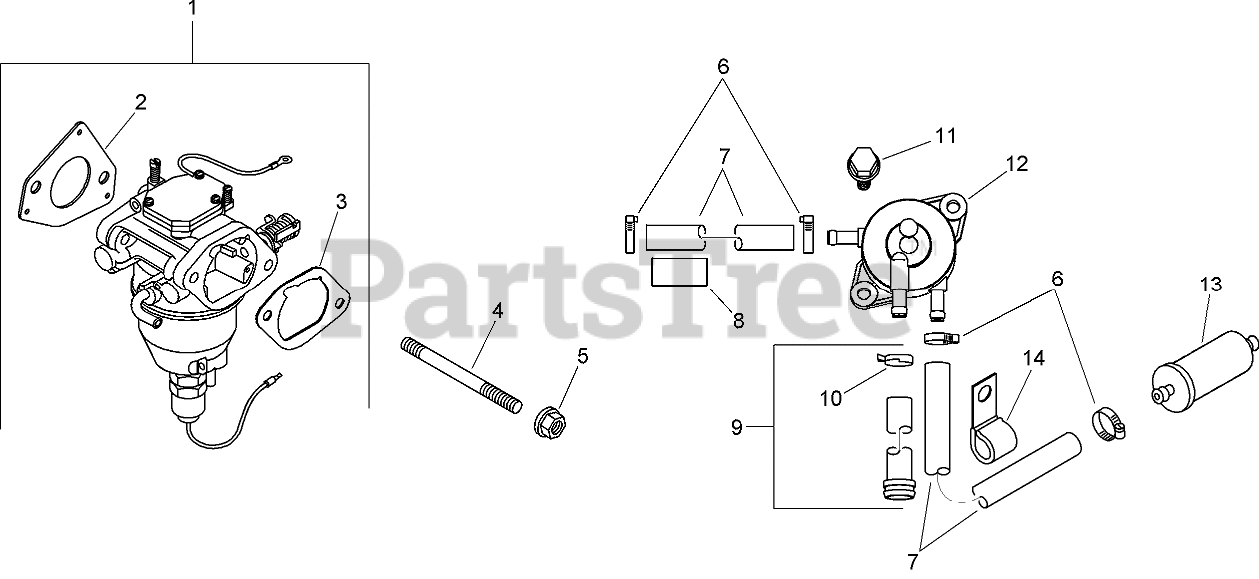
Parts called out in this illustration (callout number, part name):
1	CARBURETOR KIT W/GASKETS (INCLUDES 2, 3)
2	GASKET-CARBURETOR
3	GASKET-BASE, AIR CLEANER
4	STUD (M6X1.0X106)
5	NUT-FLANGE (M6X1.0)
6	CLAMP-HOSE, SPRING (1/2)
7	LINE-FUEL (24.0 CUT TO LENGTH)
8	SLEEVE-ABRASION, ANTI
9	FUEL PUMP HOSE ASM W/CLAMP (INCLUDES 10)
10	CLAMP-HOSE
11	SCREW-TAP (M6X1.7X18)
12	PUMP-FUEL
13	FILTER-FUEL
14	CLIP-CABLE
